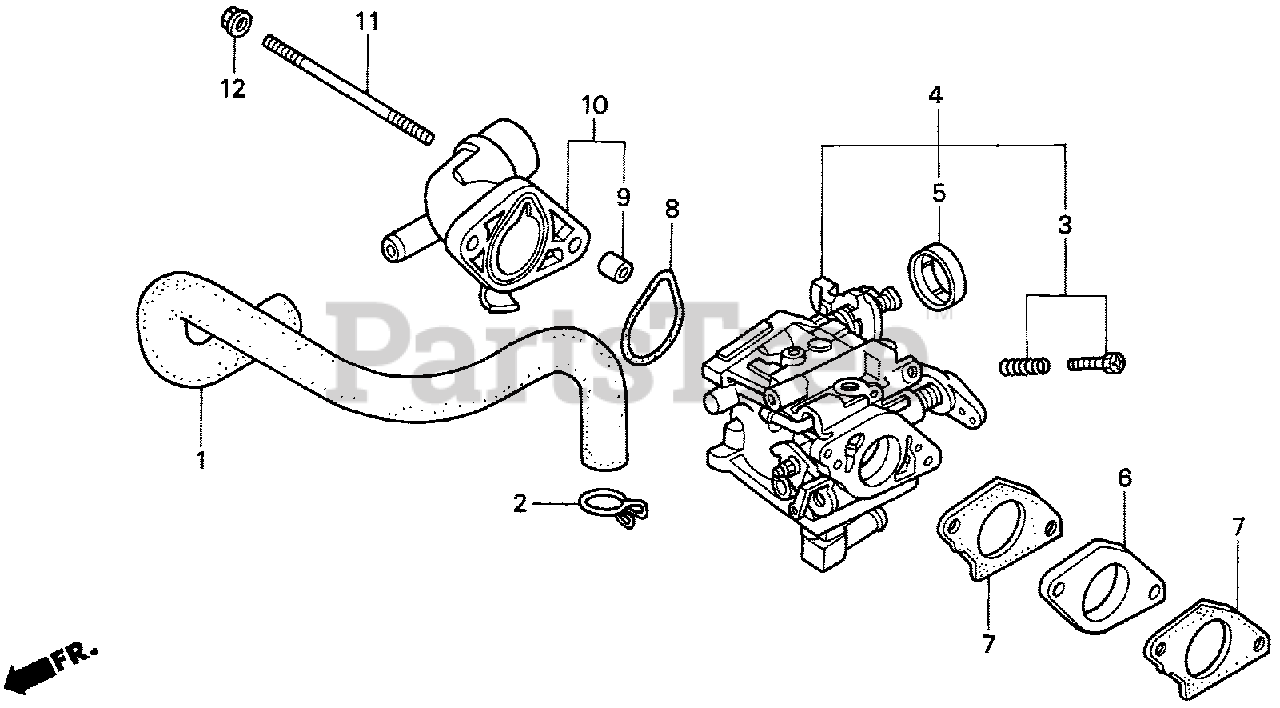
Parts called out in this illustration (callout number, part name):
1	TUBE, BREATHER
2	CLIP, BREATHER TUBE
3	SCREW SET
4	CARBURETOR ASSY. (BGL2A A)
5	CAP, CHOKE LEVER DUST
6	INSULATOR, CARBURETOR
7	GASKET, CARBURETOR
8	GASKET, AIR CLEANER
9	COLLAR A, AIR CLEANER
10	ELBOW, AIR CLEANER
11	BOLT, STUD (6X108)
12	NUT, FLANGE (6MM)
